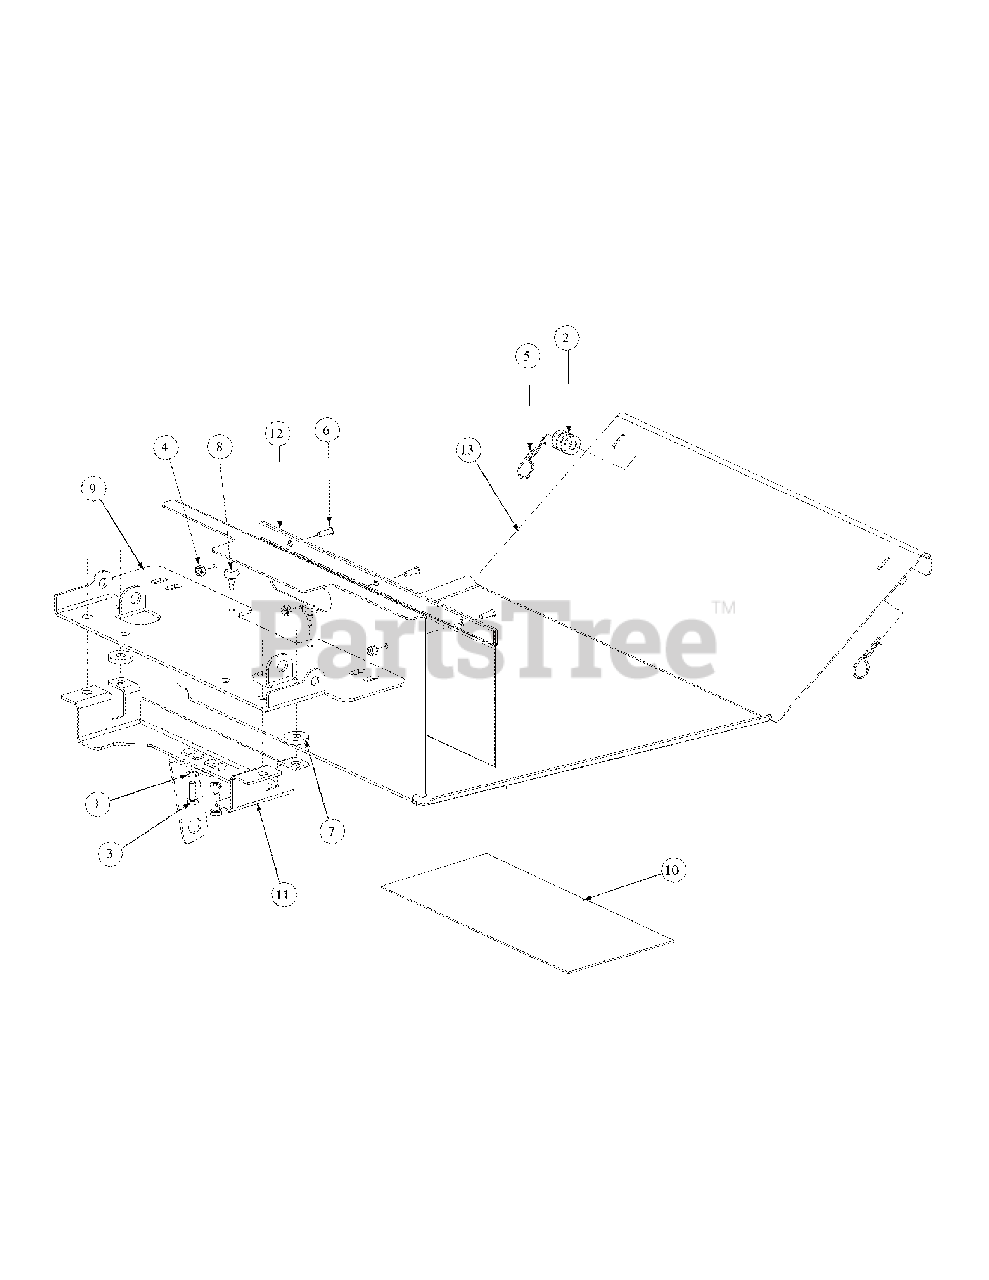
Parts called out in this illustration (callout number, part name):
1	Lock Washer, 1/4
3	Hex Cap Screw, 1/4-20, .75
4	Lock Nut, Nylon Insert, 10-32
5	Hair Pin, 3/8-1/2
6	Screw, Phillips Head, Machine, 10-32 x 5/8
7	Washer
8	Rubber Bumper, .62 OD x .22 Thick
10	Label, Belt Routing and Lubrication
11	Support, Seat Bracket
12	Bag, Debris Storage
13	Floor Panel Assembly
